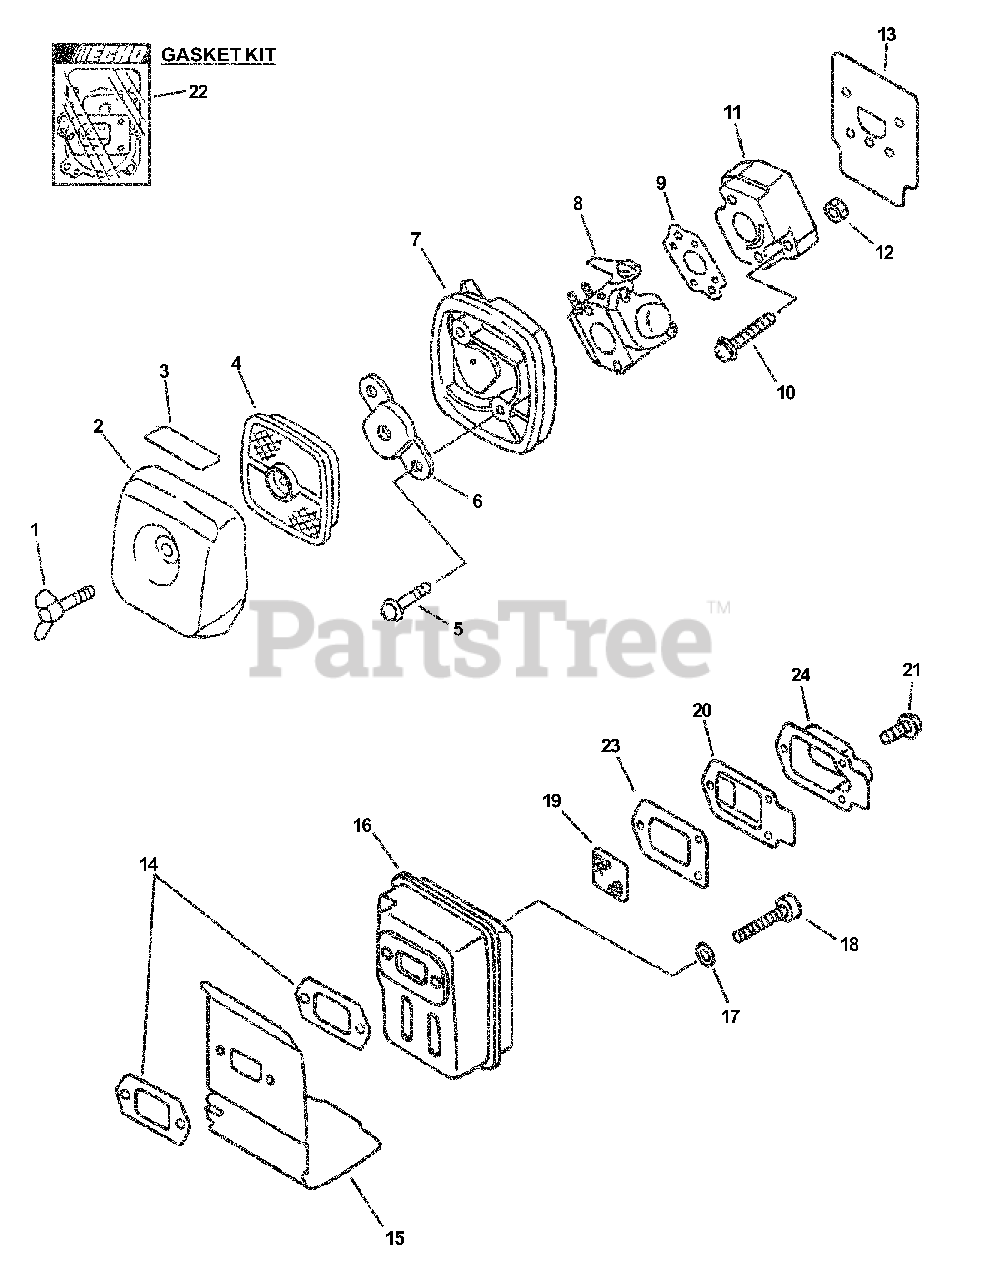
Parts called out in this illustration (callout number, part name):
1	THUMBSCREW
2	COVER, AIR FILTER - GRAY
3	LABEL - CHOKE
4	FILTER, AIR - SINGLE LAYER
5	SCREW - 5X65
6	PLATE, PREVENT
7	AIR FILTER CASE ASSY
8	CARBURETOR C1U-K47
8	CARBURETOR C1U-K52
9	GASKET, INTAKE
10	SCREW - 5X20
11	INSULATOR, INTAKE
13	SHIELD, INTAKE
14	GASKET, EXHAUST
15	SHIELD, EXHAUST
17	WASHER - 5
18	SCREW - 5X55
19	SCREEN, SPARK ARRESTOR
20	GASKET, EXHAUST - INNER
21	SCREW - 4X10
22	GASKET KIT
23	GASKET, EXHAUST
24	GUIDE, EXHAUST - OUTER
